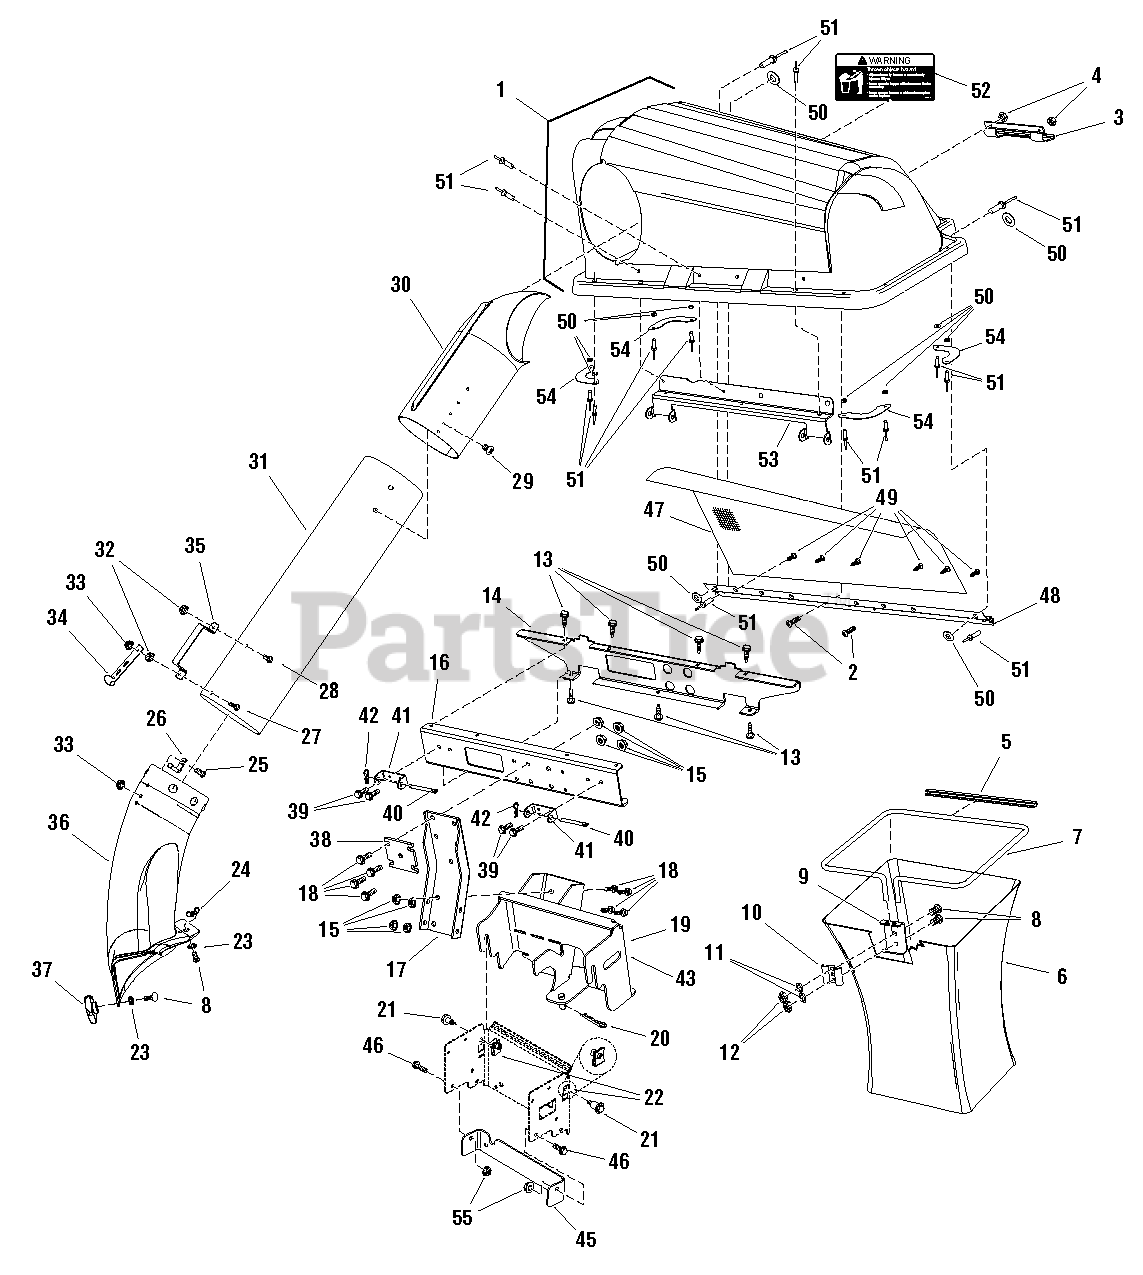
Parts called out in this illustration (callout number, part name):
1	COVER ASSEMBLY, Twin Catcher
2	SCREW, Phillips, 10 - 24 x 3/4
3	HANDLE, Plastic
4	NUT, Hex .10 - 24
5	CLIP, Tube Grass Bag
6	BAG, Grass
7	HOOP, Twin
8	BOLT, Carriage, 5/16 - 18 x 3/4, G5
9	HANGER, Grass Bag
10	CLAMP, Grass Bag
11	LOCKWASHER, Spring, 5/16
12	NUT, Hex, 5/16 - 18
13	SCREW, Hex Washer Head Taptite, 5/16 - 18 x 3/4
14	BRACKET, Cross Support, Twin
15	NUT, Hex, 3/8-16
16	CHANNEL, Cross Support Twin
17	SUPPORT, Upright
18	CAPSCREW, Hex Flange Whiz Lock, 3/8-16 x 3/4
19	SUPPORT ASSEMBLY, Catcher
20	CLIP, Hair Pin
21	BOLT, Shoulder, 5/16 - 18 x 1.62
22	NUT, Speed, 5/16 - 18
23	NUT, Push Pal
24	NUT, Wingnut
25	BOLT, Carriage, 1/4 - 20 x .625
26	PIN, Latch
27	SCREW, Machine 1/4 - 20 x 1
28	SCREW, Machine 1/4 - 20 x .50
29	SCREW, 1/7 x .75
30	ELBOW, Upper Tube
31	TUBE, Catcher
32	NUT, Hex Keps, 1/4 - 20
33	NUT, Hex Flange, 1/4 - 20
34	STRAP, Hood
35	HANDLE, Connect Tube
36	TUBE, Boot
37	KNOB
38	PLATE, Reinforcement, Upright
39	SCREW, Hex Washer Head Taptt 1/4 - 20 x.5
40	PIN, Cover Hinge
41	PIVOT, Hinge
42	CLIP, Hair Pin
43	* DECAL, ID Plate
45	PLATE, Reinforcement, Frame
46	SCREW, Hex Whiz Lock Flange, 5/16 - 18 x 1.25
47	SCREEN, Twin
48	SCREEN SUPPORT, Twin
49	FASTENER, Push .25 x .50
50	WASHER, Rivet .188
51	RIVET, Pop .188
52	DECAL, Cover Warning
53	HINGE, Cover
54	GUSSET, Support Cover
55	NUT, Hex Flange 5/16 - 18
